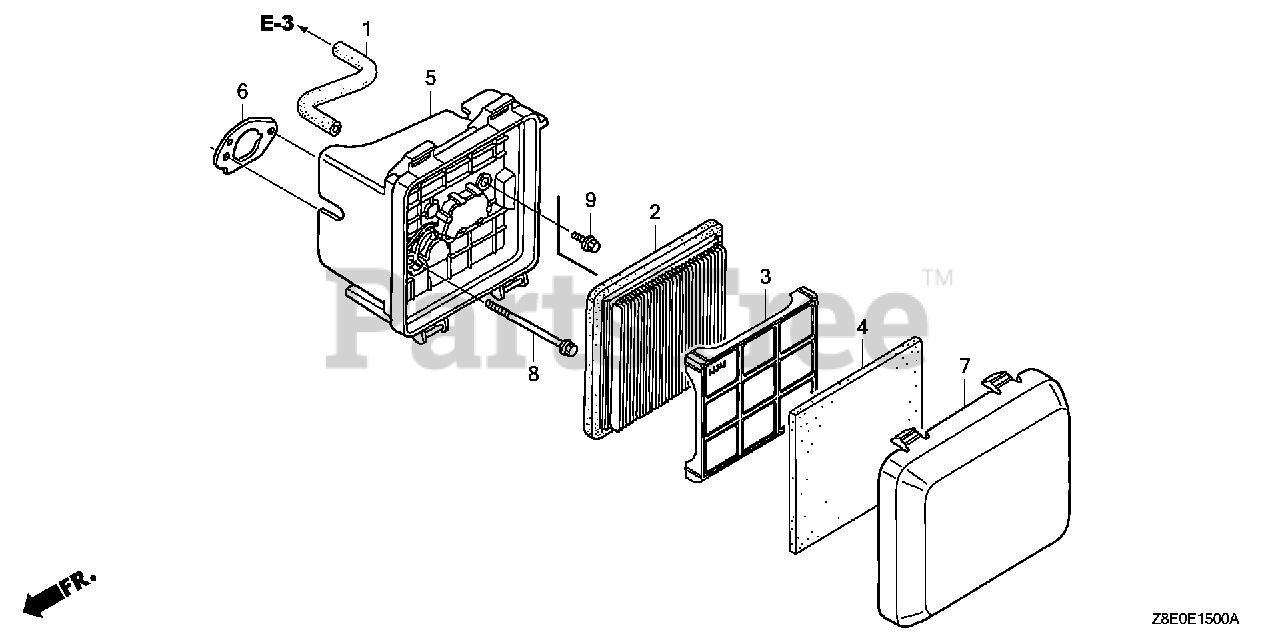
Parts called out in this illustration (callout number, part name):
1	TUBE, BREATHER
2	ELEMENT, AIR CLEANER (TOYO ROKI)
3	GRID, AIR CLEANER
4	FILTER (OUTER) (WET)
5	CASE ASSY., AIR CLEANER
6	GASKET, AIR CLEANER
7	COVER, AIR CLEANER (DUAL)
8	BOLT, FLANGE (6X86) (CT200)
8	BOLT, FLANGE (6X85) (CT200)
9	BOLT, FLANGE (6X14)
